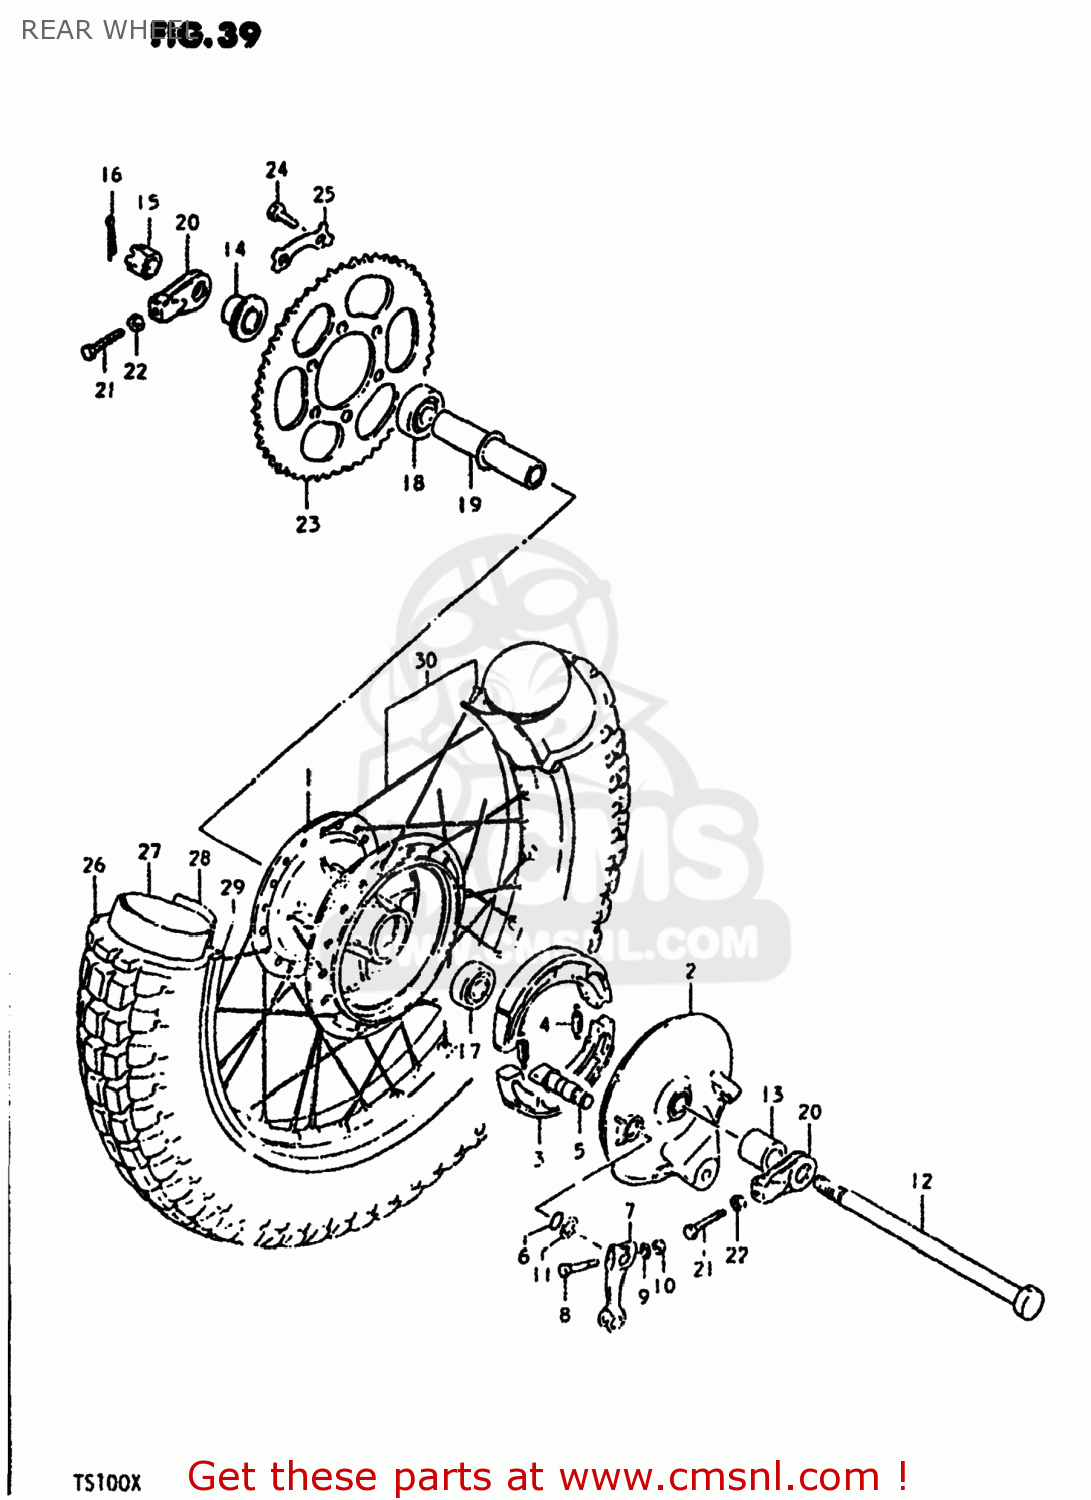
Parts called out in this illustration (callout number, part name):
1	HUB,REAR WHEEL
2	PANEL,RR BRAKE ANCHOR
3	SHOE,BRAKE
4	SPRING(L:34)
5	CAM,FRONT BRAKE
6	O-RING (D:2.4 ID:13.8)
7	LEVER,RR BRAKE CAM
8	BOLT 6X40
9	WASHER
10	NUT
11	WASHER (14.5X22X1.6)
12	AXLE,REAR
13	SPACER(15.2X22X26)
14	SPACER,RR AXLE,L
15	NUT
16	COTTER PIN
17	BEARING
18	BEARING
19	SPACER,RR WHEEL HUB BEARING
20	ADJUSTER,CHAIN,R
21	BOLT(8X40)
22	NUT
23	SPROCKET,RR
24	BOLT(8X30)
25	WASHER
26	TIRE 3.00-18 077-458MM
27	TUBE,INNER
28	PROTECTOR,INNER TUBE
29	RIM,RR WHEEL
30	SPOKE SET
